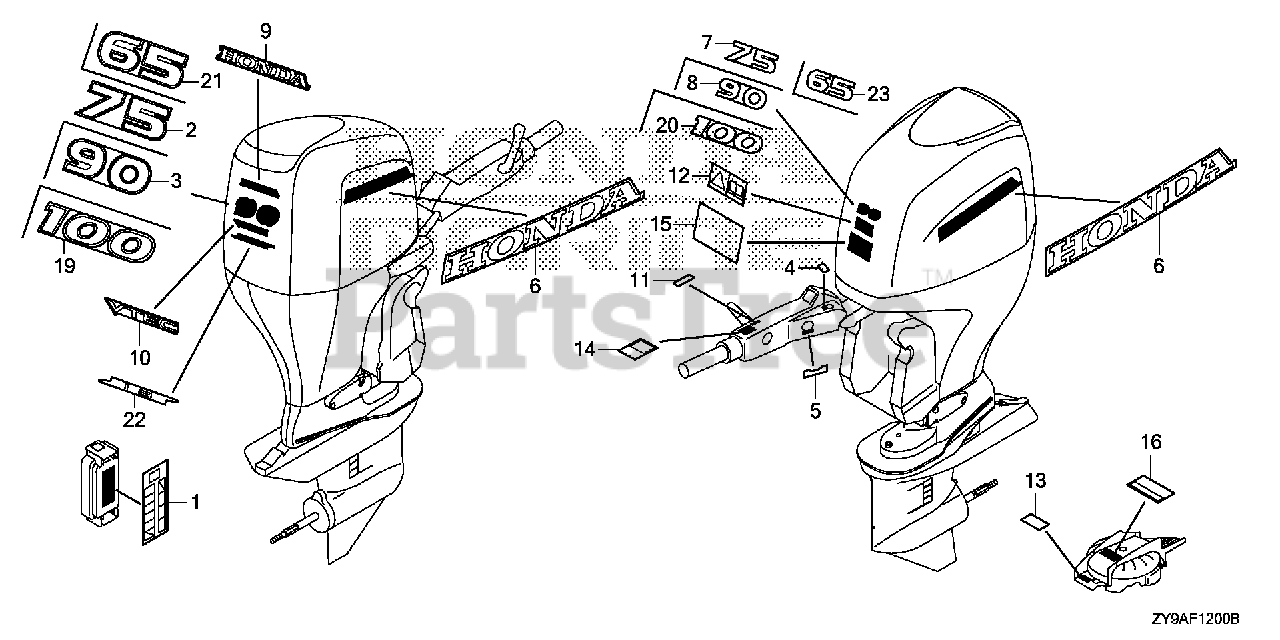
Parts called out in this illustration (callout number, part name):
1	LABEL, FUSE
6	MARK, SIDE STRIPE
9	MARK, HONDA
10	MARK (VTEC)
13	LABEL, CAUTION OIL (ENGLISH)
15	LABEL, WARNING OPERATOR (ENGLISH)
16	MARK, EMERGENCY START (ENGLISH)
19	MARK, RR. (100)
20	MARK, FR. EMBLEM (100)
